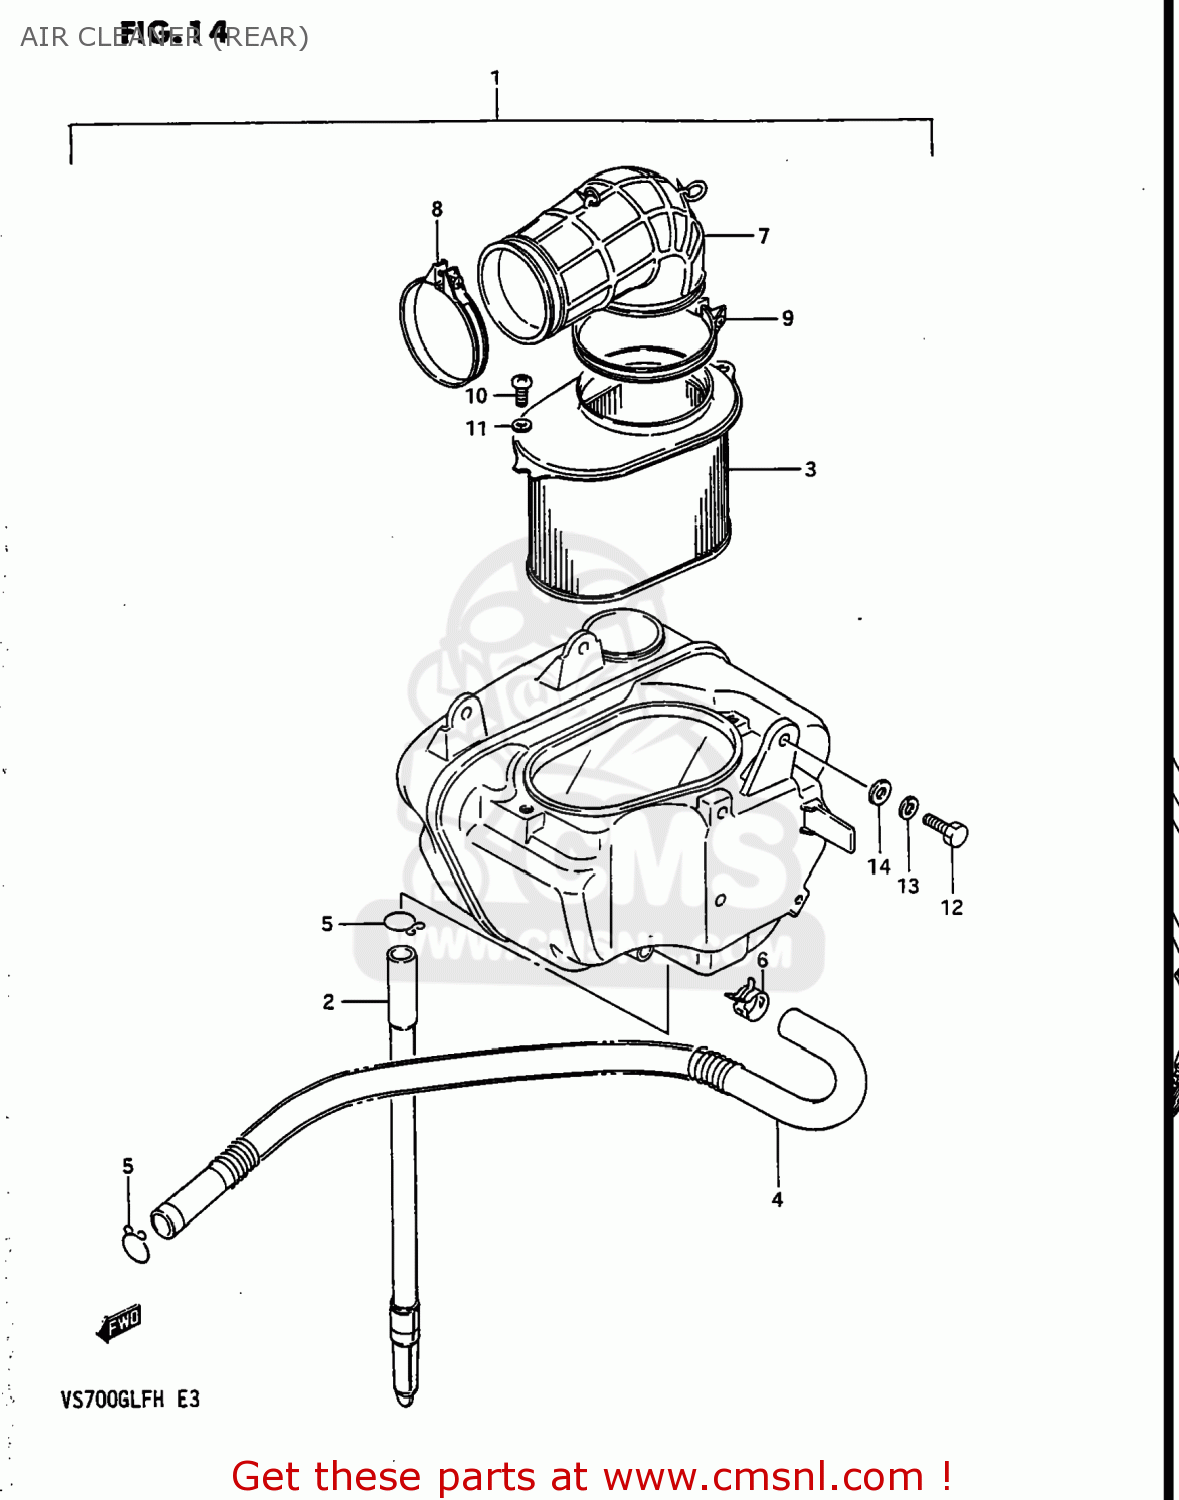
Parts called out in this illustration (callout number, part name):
1	CLEANER ASSEMBLY,AIR
2	DRAIN TUBE
3	FILTER,AIR CLEANER
4	TUBE SET,BREATHER
5	CLIP
6	CLIP
7	TUBE,AIR CLEANER OUTLET
8	CLAMP
9	CLAMP
10	SCREW
11	WASHER,LOCK
12	BOLT
13	WASHER,LOCK
14	WASHER(6.5X16X1.2)
